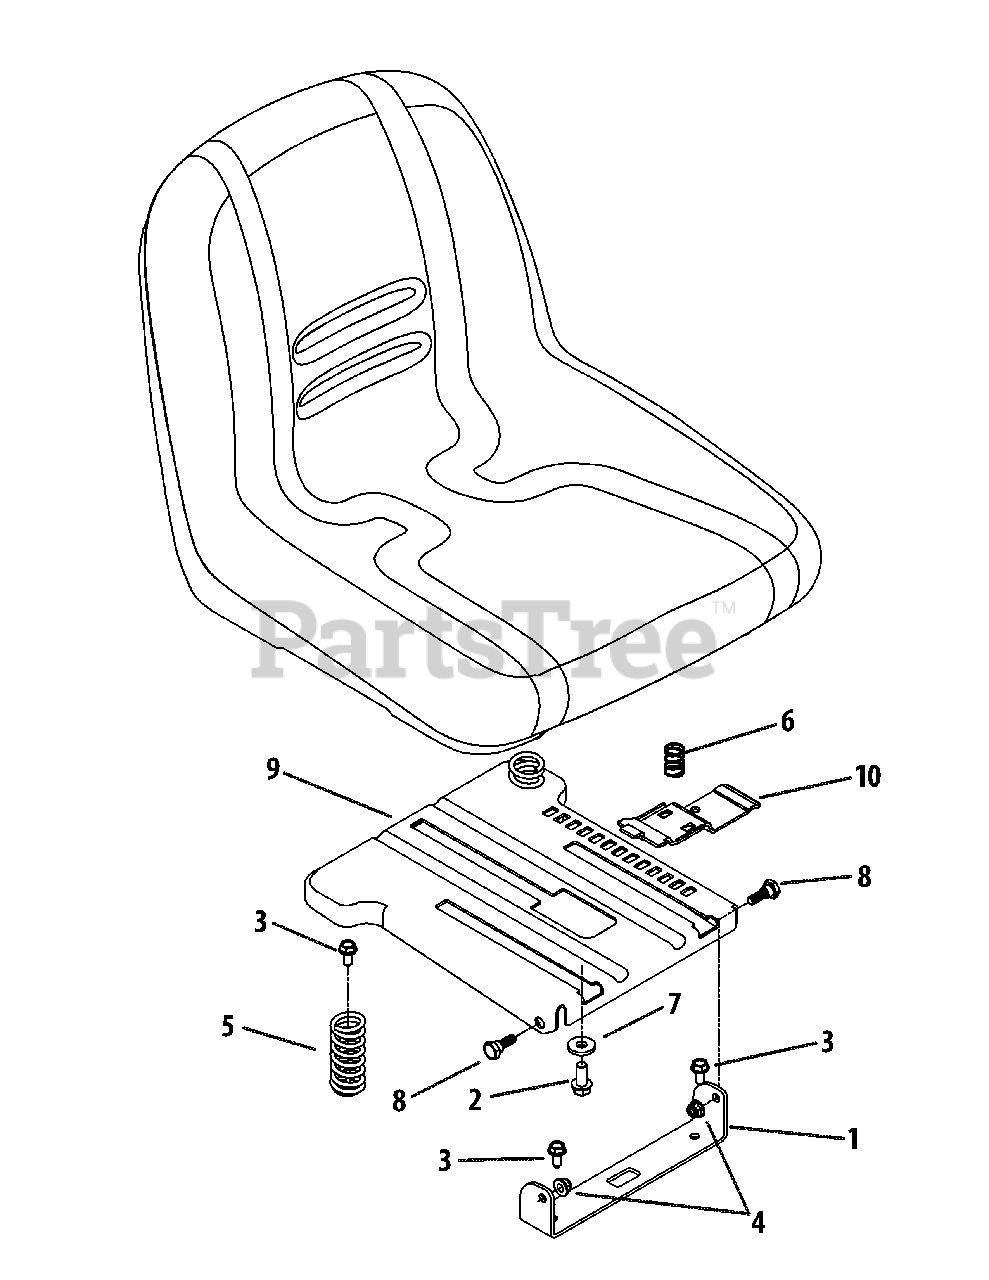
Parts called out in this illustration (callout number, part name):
2	Hex Flange Bolt, 3/8-16 x .875
3	Hex Washer Screw, 5/16-18 x .750
4	Flange Lock Nut, 5/16-18
5	Compression Spring
6	Compression Spring
7	Flat Washer, .385 x 1.0 x .135
8	Shoulder Screw, .437 x .268 x 5/16-18
9	Seat Mount Bracket
10	Seat Adjustment Lever
